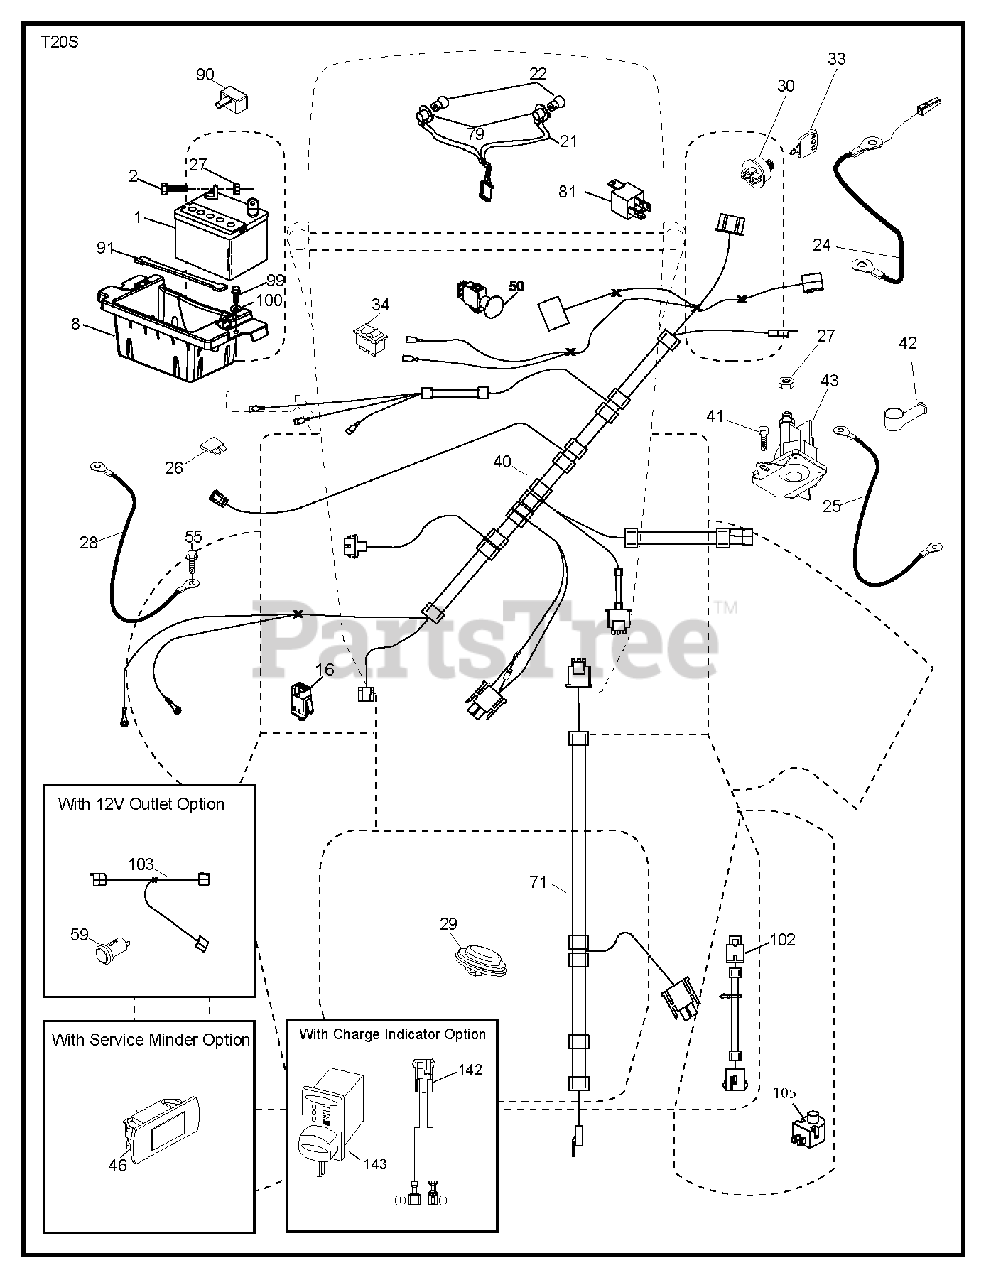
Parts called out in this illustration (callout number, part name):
1	REPL BY 532 12 38-99
8	BOX.BATTERY.MOUNT.FRONT.LT
16	SWITCH INTERLOOK PUSH-IN
21	HARNESS.LIGHT W/4152J BULBS
22	LIGHTBULB
24	Battery Cable with Wire, Front 8 Ga 8
25	Starter Cable, 8 Ga 17.5"
26	FUSE 20AMP
27	NUT
28	Ground Cable, 21" Black 8 Ga 90T
29	SWITCH.SEAT.DELTA.OPC.
30	SWITCH.IGN.DELTA.W.LGH.ROS
33	KEY.CHAIN.BLISTER.PACK.GEN.INT
34	SWITCH LT
40	HARNESS.IGN.ELE.RELAY.TEX.46"
41	SCREW
42	TERMINAL COVER
43	SOLENOID.W/BRASS.PLUNG
46	Hour Meter Gauge
50	PTO SWITCH
55	SCREW 5/16"
71	HARNESS-CHASSIS SUB
79	BULB HOLDER ASM.
81	RELAY HARNESS.SEALED
90	COVER.TERMINAL.BATTERY
91	STRAP, BATTERY MOUNT
99	SCREW HEXWSHR 1/4-20X3/4
102	HARNESS PIGTAIL PCH TEX ROS
105	REVERSE SWITCH
